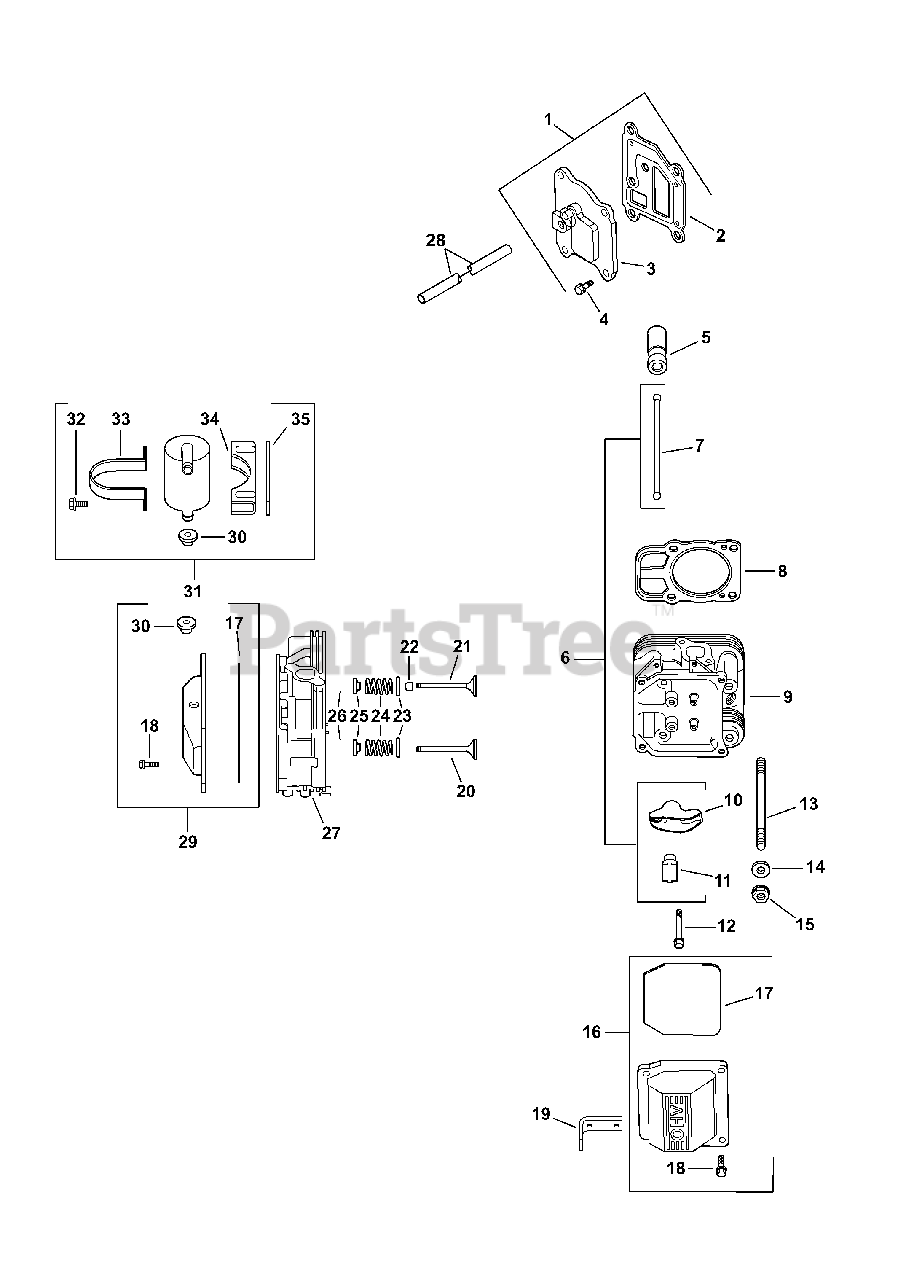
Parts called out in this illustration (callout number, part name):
1	Kit, Breather Cover W/Gasket (Includes 2-4)
2	Gasket, Breather
3	Cover, Breather
4	Screw, Flg Thd Frm M6x1.0x20
5	Hydraulic Valve Lifter
6	Kit, Valve Train (Includes 7,10,11)
8	Kit, Cylinder Head Gasket
9	Kit, #2 Cylinder Head Assy
11	Pivot, Rocker Arm
12	Screw, Flg M6x1.0x34
13	Stud, M8x1.25, M10x1.5, 105mm
14	Washer, Flat 8.6 Mm
15	Nut, Flg M8x1.25
16	Kit, Plain Rocker Cover (Includes 17,18)
17	O-Ring, Valve Cover
18	Screw, Flg M6x1.0x30
19	Strap, Lifting
20	Valve, Exhaust (Std)
20	Valve, Exhaust (.25)
21	Valve, Intake (Std)
21	Valve, Intake (.25)
22	Seal, Valve Stem
23	Retainer, Spring
24	Spring, Valve
25	Cap, Valve Spring
26	Kit, Retainer
27	Kit, #1 Cylinder Head Assy
28	Hose, Breather
29	Kit, Breather Rocker Cover (Includes 17,18,30)
30	Grommet, Rubber
31	Kit, Breather Separator (Inc. 30-35)
32	Screw, Flg Thd Frm M5x0.8x16
33	Strap, Breather
34	Bracket, Breather Separator
